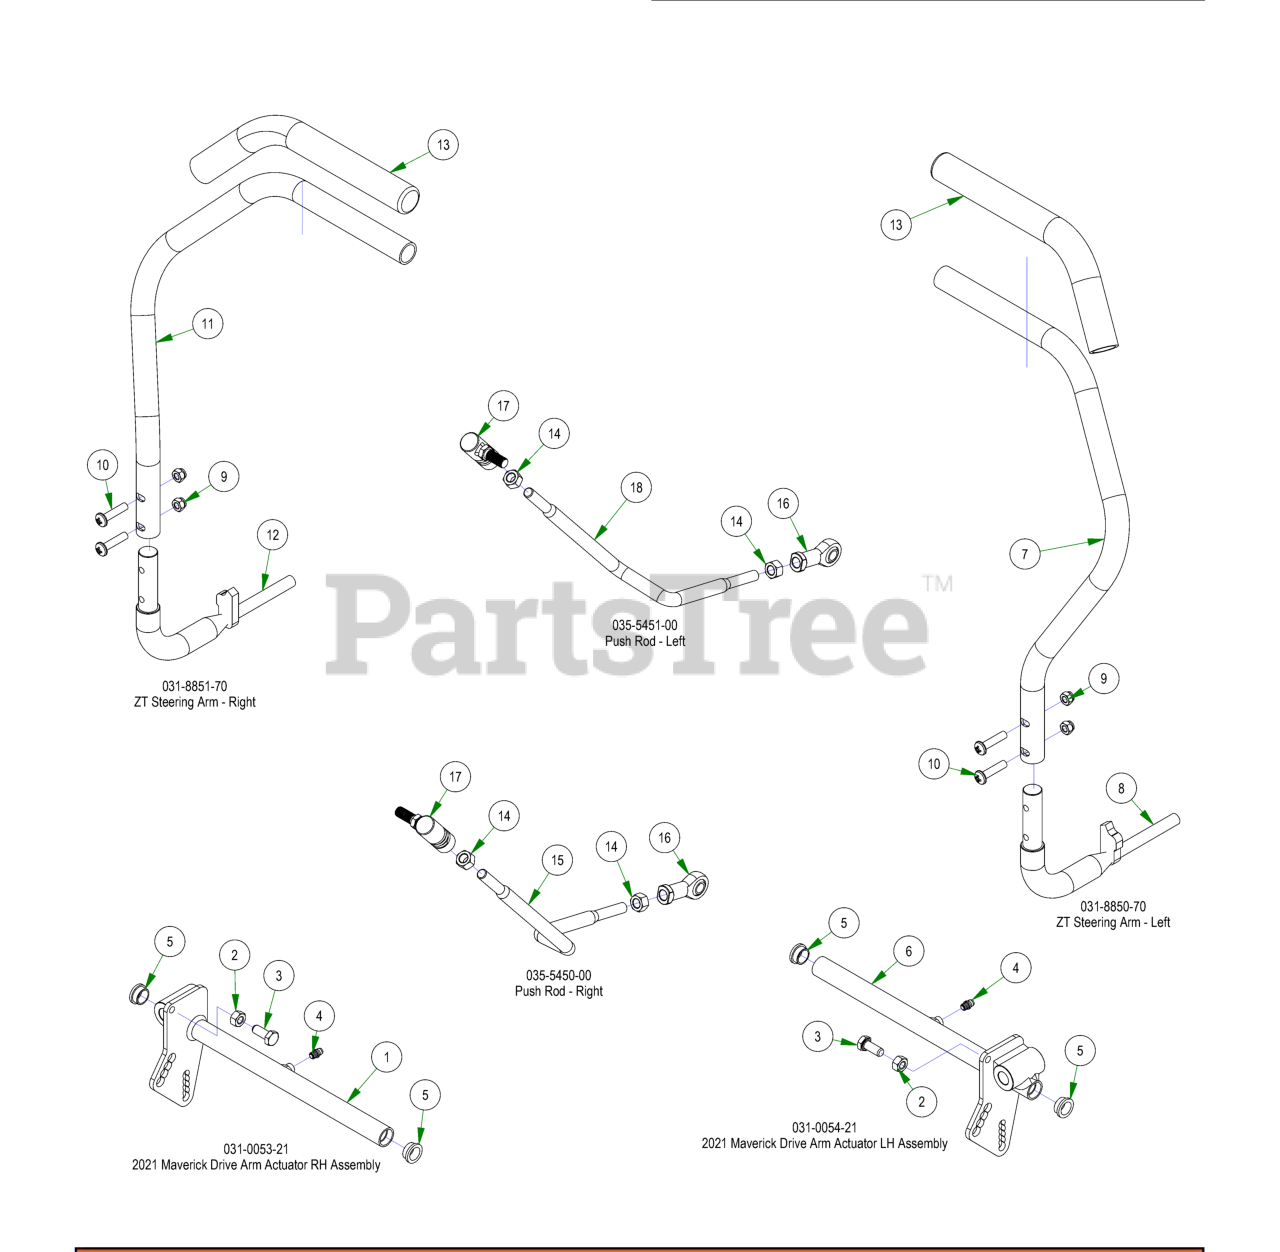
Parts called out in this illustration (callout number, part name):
1	2021 Drive Actuator RH Weldment
2	5/16-18 HEX NUT ZINC
3	5/16-18 X 3/4 HEX CAP SCREW (GR.5) ZINC
4	1/4" Press in Grease Fitting
5	2019 Drive Arm Bushing
6	2021 Drive Actuator LH Weldment
7	ZT Direction Steering Arm (Left)
8	Steering Arm Elbow (Left)
9	5/16-18 NYL INS L/N ZC
10	5/16-18 x 1 3/8" Futton Head Torx Drive Bolt
11	ZT Direction Steering Arm (Right)
12	Steering Arm Elbow (Right)
13	Rubber Grip
14	3/8" Fine Threaded Jam Nut
15	Push Rod - Right (Rod Only)
16	Spherical Rod End - Outlaw
17	Quick Release Ball Joint
18	Push Rod LH (Rod Only)
